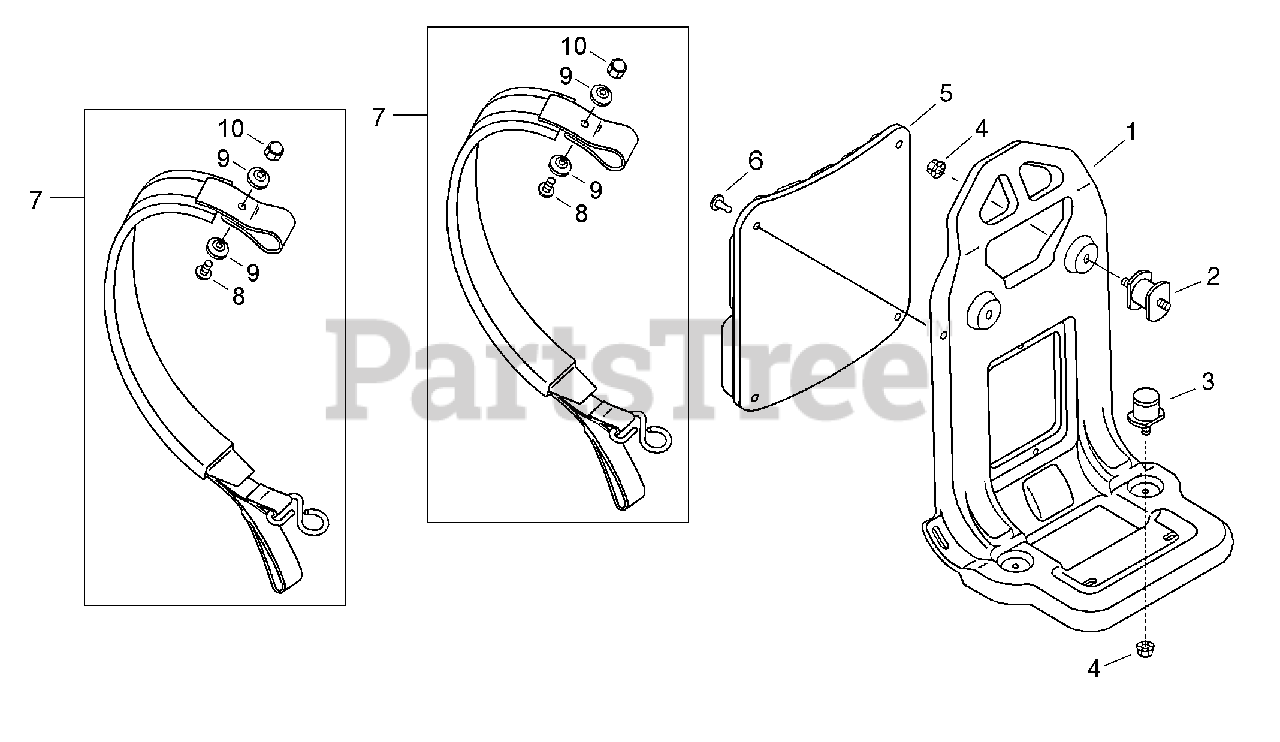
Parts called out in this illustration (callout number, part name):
1	FRAME, BACKPACK
5	CUSHION, BACKPACK
7	STRAP ASSY
8	SCREW - 5X16
10	LOCKNUT - 5
